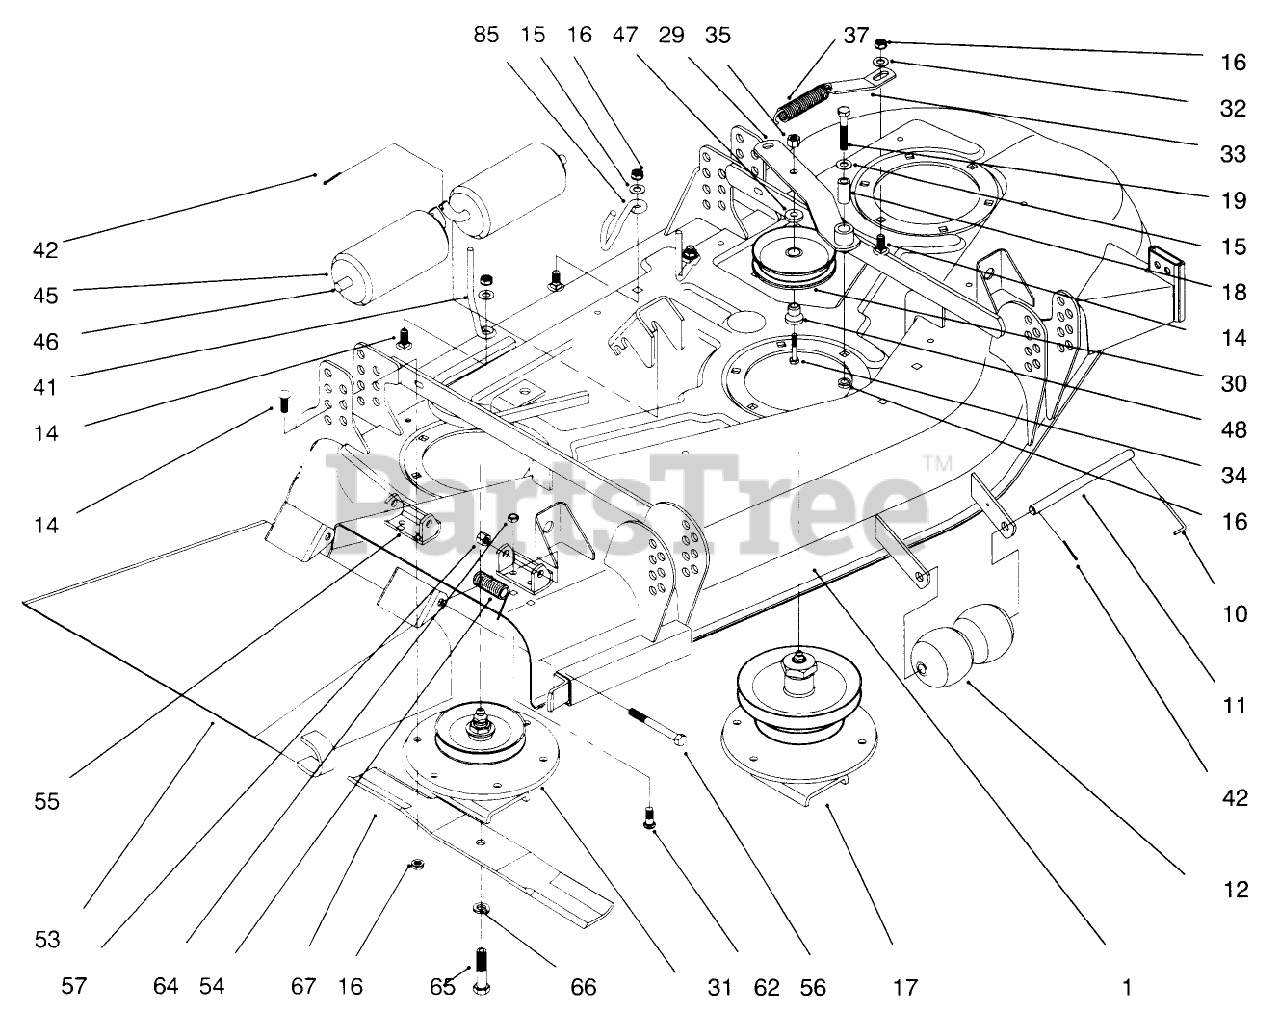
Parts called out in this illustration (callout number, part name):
10	PIN-SPECIAL
11	SHAFT-ROLLER
12	ROLLER
14	SCREW-CARR
15	WASHER-FLAT
16	NUT-HF
17	HOUSING - SPINDLE ASM
18	SLEEVE
19	SCREW-HH
29	IDLER ARM ASM
30	PULLEY-IDLER
31	SPINDLE ASM
32	WASHER-FLAT
33	PLATE-SPRING
34	SCREW-HH
35	NUT-HEX
37	Spring-Idler
41	ROD-BELT
42	PIN-COTTER
45	ROLLER-DECK
46	SHAFT-ROLLER, REAR
47	WASHER-FLAT
48	BUSHING-PULLEY
53	Deflector
54	SPRING
55	BRACKET-PIVOT
56	SCREW-HH
57	NUT-HEX
62	SCREW-CARR
64	NUT-LOCK, CONE
65	SCREW-BLADE
66	WASHER-LOCK
67	BLADE
85	GUIDE-BELT
